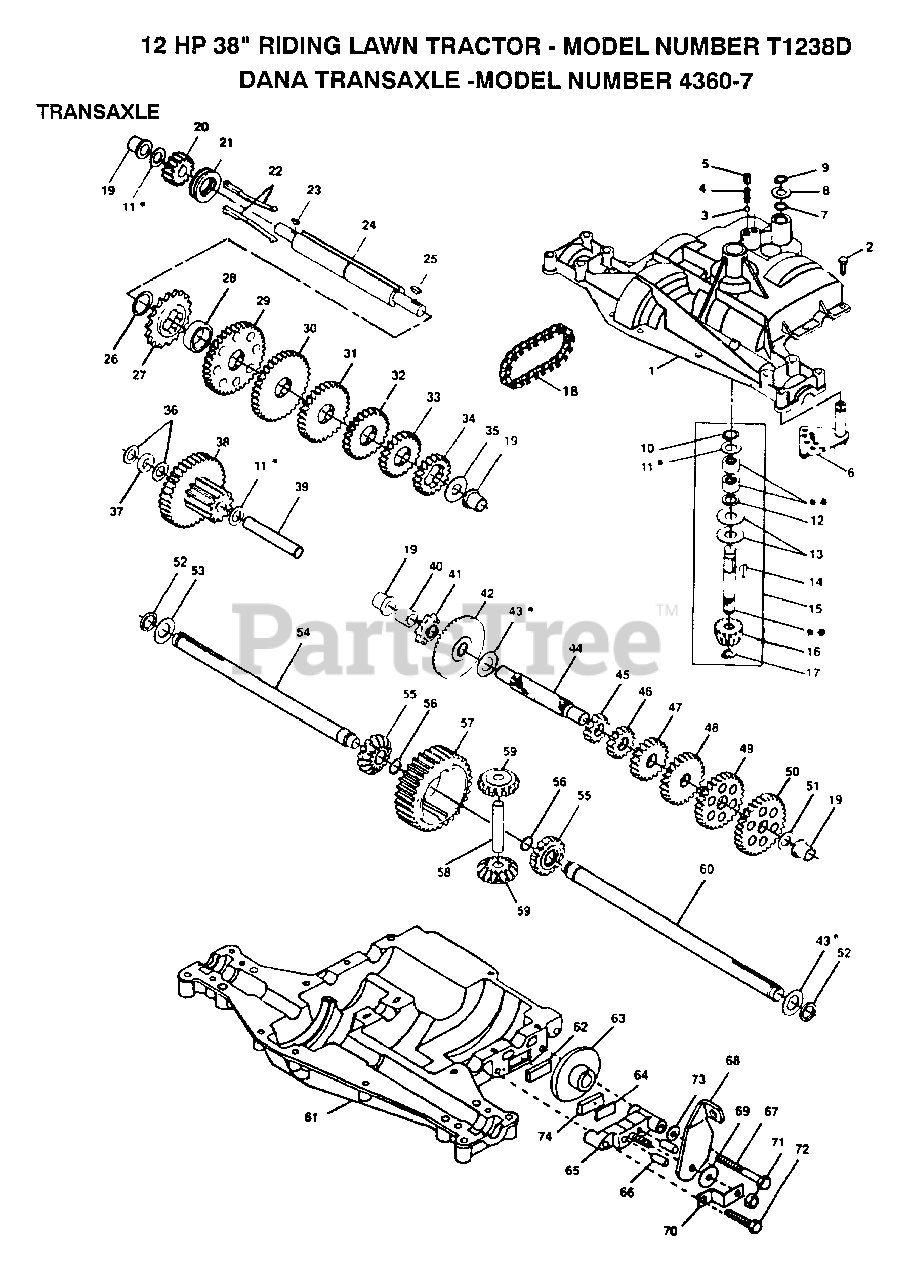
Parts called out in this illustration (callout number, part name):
1	HOUSING UPPER
3	BALL DETENT
4	SPRING, DETENT
5	SCREW, SET
6	ASSY SHIFTER
8	WASHER PLAIN
9	RING RETAINING
10	RING RETAINING
11	WASHER PLAIN
13	WASHER, PLAIN .632 X 1.38 X .046
14	KEY WOODRUFF #9
15	ASSY KIT INPUT SHAFT
16	PINION, BEVEL, 14 TEETH
17	RING, RETAINING
18	CHAIN, 24 PITCHES
19	BEARING, FLANGE
20	GEAR SPUR, 14 TEETH
21	COLLAR CLUTCH
22	KEY CLUTCH
23	KEY WOODRUFF #3
24	SHAFT INTERMEDIATE
25	KEY, WOODRUFF, #61
26	RING, RETAINING
27	SPROCKET, 18 TEETH
29	GEAR, SPUR, 37 TEETH
30	GEAR, SPUR, 35 TEETH
31	GEAR, SPUR, 30 TEETH
32	GEAR, SPUR, 25 TEETH
33	GEAR, SPUR, 22 TEETH
35	WASHER, PLAIN .640 X 1.37 X .061
36	WASHER, PLAIN .632 X 1.00 X .026
37	SPACER .630 X 1.00 X .169
38	ASSY GEAR COMB 12&35 TEETH
39	SHAFT IDLER
40	SPACER .635 X .875 X .755
41	SPROCKET, 9 TEETH
42	GEAR, BEVEL, 42 TEETH
43	WASHER PLAIN
44	SHAFT, DRIVE
45	GEAR, SPUR, 12 TEETH
46	GEAR SPUR, 15 TEETH
47	GEAR, SPUR, 20 TEETH
48	GEAR, SPUR, 25 TEETH
49	GEAR, SPUR, 28 TEETH
50	GEAR, SPUR, 31 TEETH
51	WASHER, PLAIN .632 X 1.00 X .060
53	WASHER PLAIN
54	AXLE LEFT HAND
55	GEAR, MITER, 15 TEETH
56	RING, RETAINING
57	GEAR, SPUR, 32 TEETH
58	SHAFT, CROSS
59	GEAR, MITER, 15 TEETH
60	AXLE, R.H.
61	HOUSING LOWER
62	PUCK, FRICTION
63	DISC, BRAKE
65	JAW, BRAKE
66	PIN, DOWEL
67	SCREW TAPPING
68	LEVER, ACTUATING
69	WASHER, PLAIN .321 X 1.00 X .055
70	BRACKET, ANTI-ROTATION
71	LOCKNUT 5/16-24
72	SCREW TAPPING
73	WASHER PLAIN
74	PUCK, FRICTION
